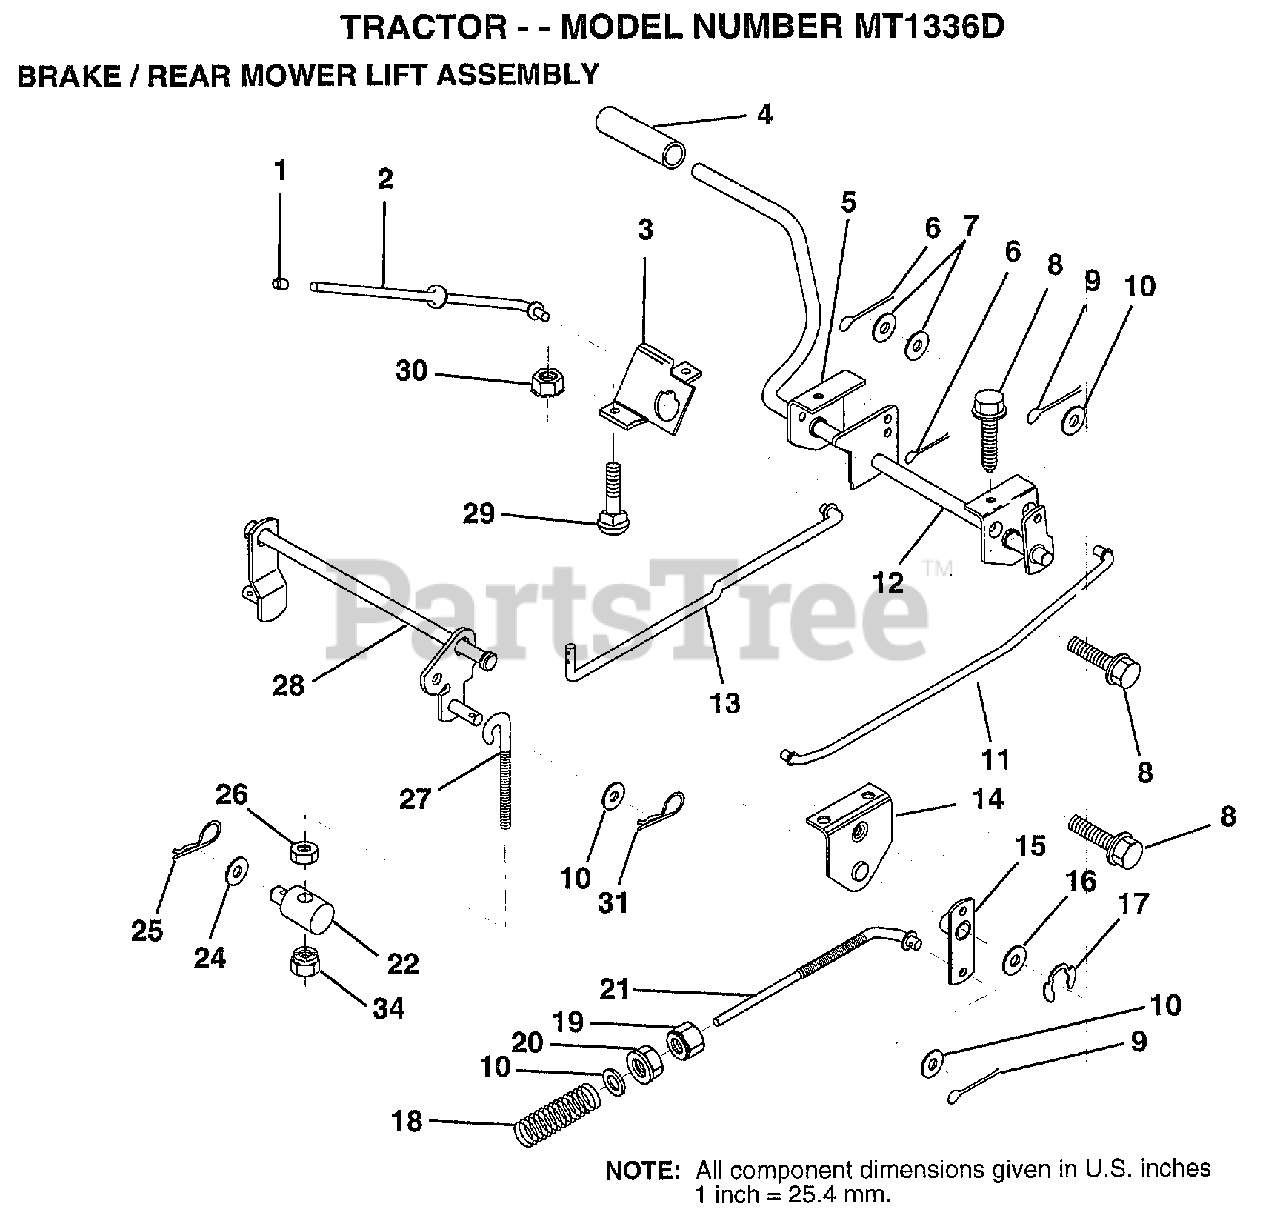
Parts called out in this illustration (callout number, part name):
1	PLUNGER CAP T
2	"ROD,PARK BRAKE"
3	"BRKT,PARK BRAKE"
4	"COVER,PEDAL"
5	"BRKT,CLU PEDAL LH"
7	WASHER
8	SCREW LT
9	COTTER PIN
10	WASHER
11	"ROD,FRT BRAKE"
12	PEDAL ASM CL/BK36
13	"ROD,CLUTCH"
14	"BRKT,LIFT SHAFT"
15	PVT BRAKE ARM ASM
16	WASHER T
17	KLIP RING
18	SPRING ROD BRAKE
19	NUT
20	NUT
22	TRUNNION.LIFT.
24	WASHER
25	SPRING.RETAINER
26	LOCKNUT
27	"LINK, MOWER REAR"
28	LIFT ASM MOW REAR
31	RETAINER.SPRING
